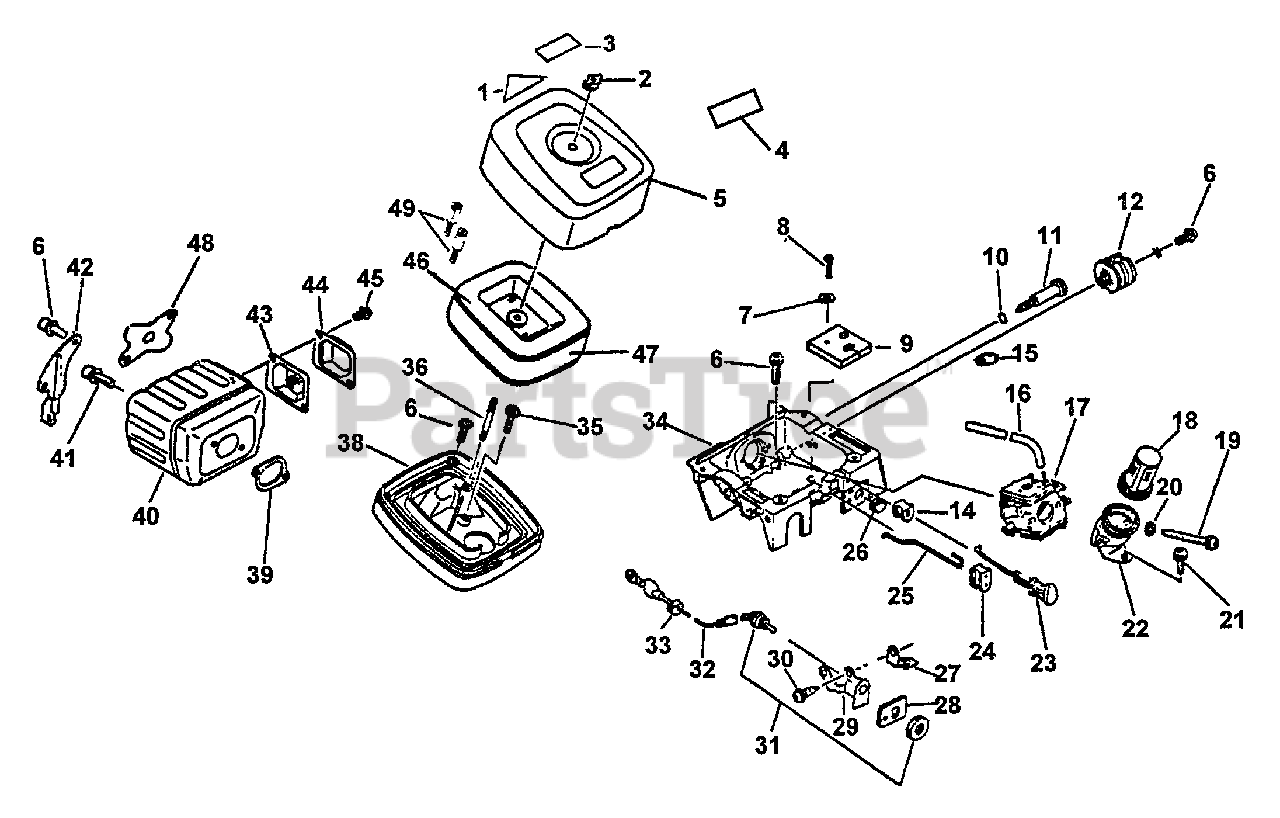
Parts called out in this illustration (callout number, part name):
2	NUT
3	LABEL - CAUTION
4	LABEL - MODEL
5	COVER, AIR FILTER
6	SCREW - 5X14
8	PIN, SPLIT - 3X18
9	PAD, FOAM
10	O-RING - 7
11	SCREW, IDLE ADJUST
14	GROMMET
16	PIPE - IMPULSE
17	CARBURETOR HDA-85
18	SCREEN, DEBRIS
19	SCREW - 5X55
20	WASHER - 5
21	SCREW - 5X14
22	MOUNT, AIR FILTER
23	ROD, CHOKE
24	GUIDE, THROTTLE ROD
25	ROD, THROTTLE
27	TERMINAL - GROUND
28	LABEL - SWITCH
29	BRACKET, SWITCH
30	SCREW - 5X10
31	IGNITION SWITCH ASSY
32	LEAD - GROUND
34	CASE, CARBURETOR
35	SCREW - 5X25
38	CASE, AIR FILTER
39	GASKET, EXHAUST
40	MUFFLER
41	SCREW - 5X20
42	BRACKET, MUFFLER
43	SCREEN, SPARK ARRESTOR
44	GUIDE, EXHAUST
45	SCREW - 4X10
46	FILTER, AIR
47	FILTER, AIR
48	COVER, MUFFLER
49	SCREW - 5X16
